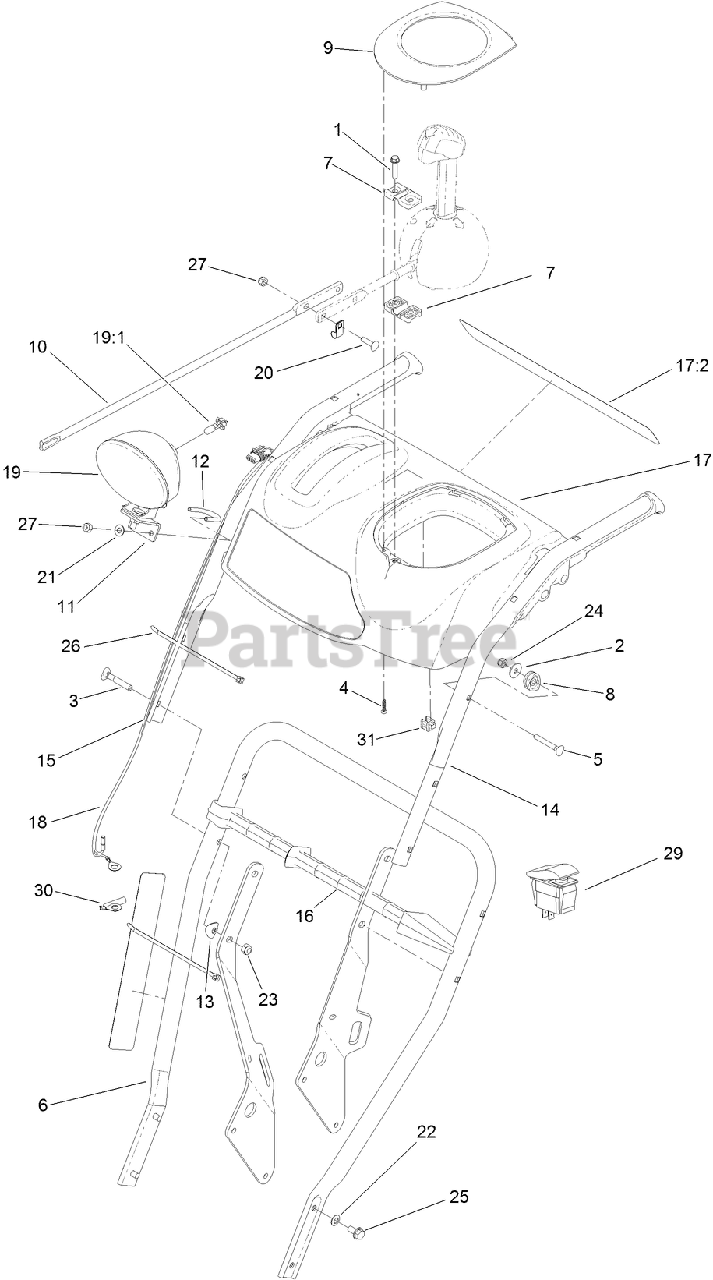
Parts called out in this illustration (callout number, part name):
1	SCREW-PLASTITE, HWH
2	WASHER-PLAIN
3	SCREW-HANDLE
4	SCREW-PPH
5	BOLT-CARR
6	HANDLE-LOWER
7	SUPPORT-ROD
8	CLAMP-CABLE
9	COVER-PANEL, CONTROL
10	ROD-CHUTE, FRONT
11	BRACKET-LIGHT
12	CLAMP-LIGHT
13	WASHER-CUP
14	HANDLE-UPPER, LH
15	HANDLE-UPPER, RH
16	STICK-CLEANOUT
17	CONTROL PANEL ASM
17:2	DECAL-CONTROL
18	HARNESS-WIRE, HEATED GRIPS
19	HEADLAMP ASM
19:1	LAMP-12 VOLT
20	BOLT-CARR
21	WASHER-PLAIN
22	WASHER-BELLEVILLE
23	NUT-HEX
24	NUT-HEX
25	SCREW-HWHTF
26	TIE-CABLE
27	NUT-HEX
29	SWITCH-ROCKER, OFF-NONE-ON
30	HARNESS-WIRE, GROUND JUMPER
31	CLIP-EDGE
